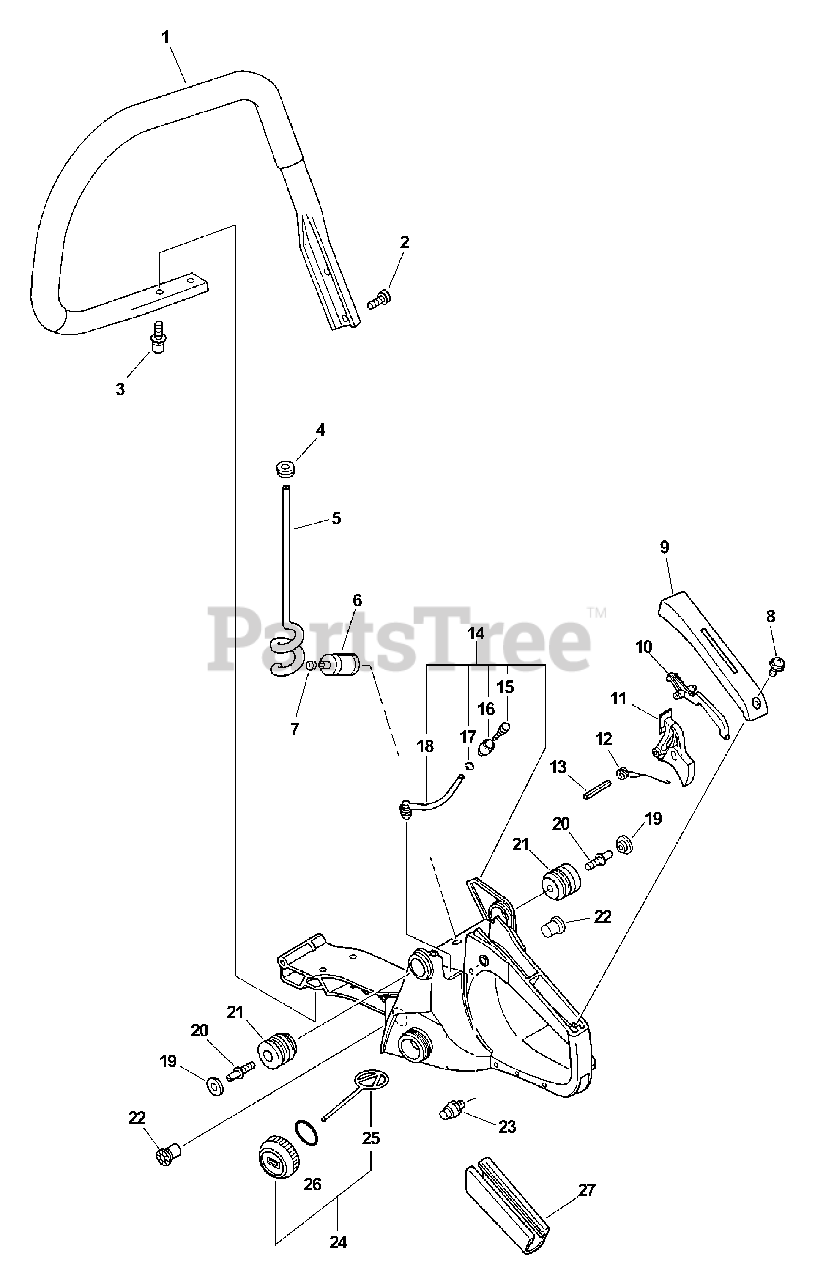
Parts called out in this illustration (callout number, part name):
1	HANDLE, FRONT
2	SCREW TAPPING 5×20
3	SCREW TAPPING 5×16
5	PIPE, FUEL 3×6×165
6	FILTER, FUEL
7	CLIP Ø6.5 MM
8	SCREW 4×14
9	COVER, HANDLE
10	LEVER, THROTTLE LOCKOUT
11	TRIGGER, THROTTLE
12	SPRING, THROTTLE RETURN
13	PIN, SPRING 4×30
14	REAR HANDLE ASSY
15	VENT ASSY
16	HOLDER, VENT
17	CLIP Ø6.5 MM
18	PIPE, VENT - GROMMET
19	CAP, CUSHION
21	CUSHION 5
22	CUSHION 5
23	LOCK, THROTTLE TRIGGER
24	CAP ASSY, FUEL
25	CONNECTOR, CAP L= 60 MM
26	O-RING 22
27	GRIP, HANDLE
